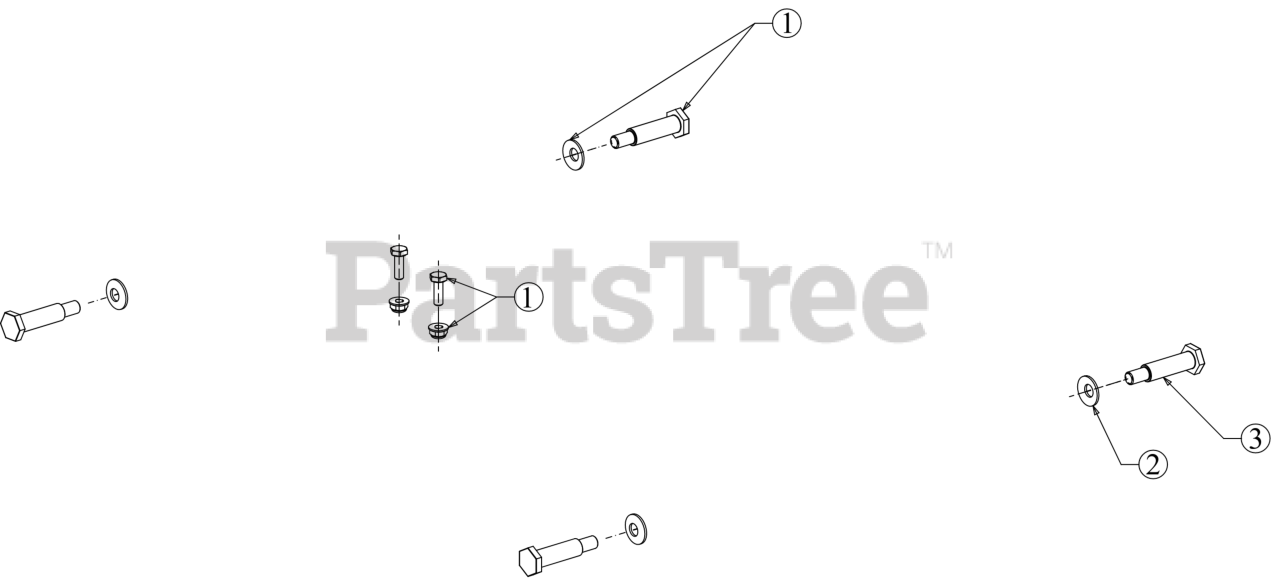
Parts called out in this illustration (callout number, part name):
1	HARDWARE PACK
1	SCREW 1/4-20X.75 GR5
1	FLANGE LOCK NUT
1	BELL WASHER .400 ID x .88 x .060
1	SHOULDER SCREW
2	BELL WASHER .400 ID x .88 x .060
3	SHOULDER SCREW
